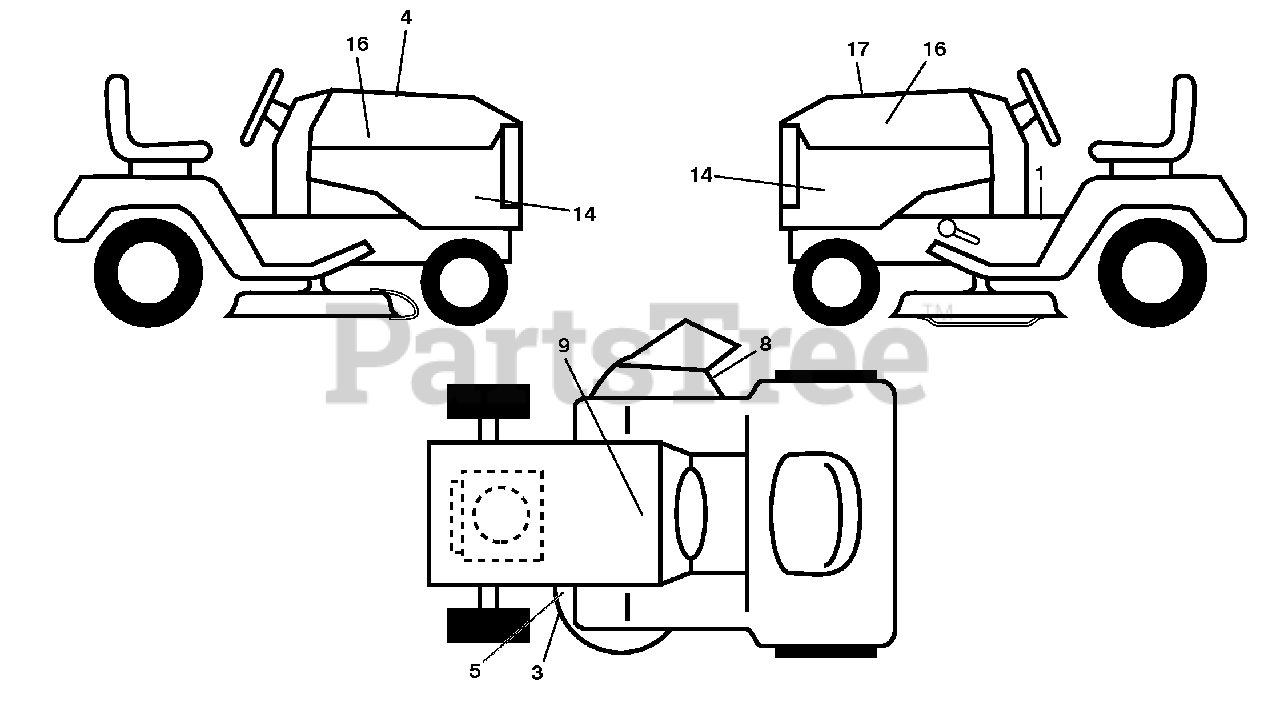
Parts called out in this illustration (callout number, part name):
1	Decal, Fender Warning
3	Decal, Warning
4	Decal, Hood Cust Resp
5	Decal, Mower Caution Tension
8	Decal, Mower Sch.
9	Decal, Battery Dnge/Poi
14	Decal, Panel Side
16	Decal, Hood Logo
17	Decal, Replacement
